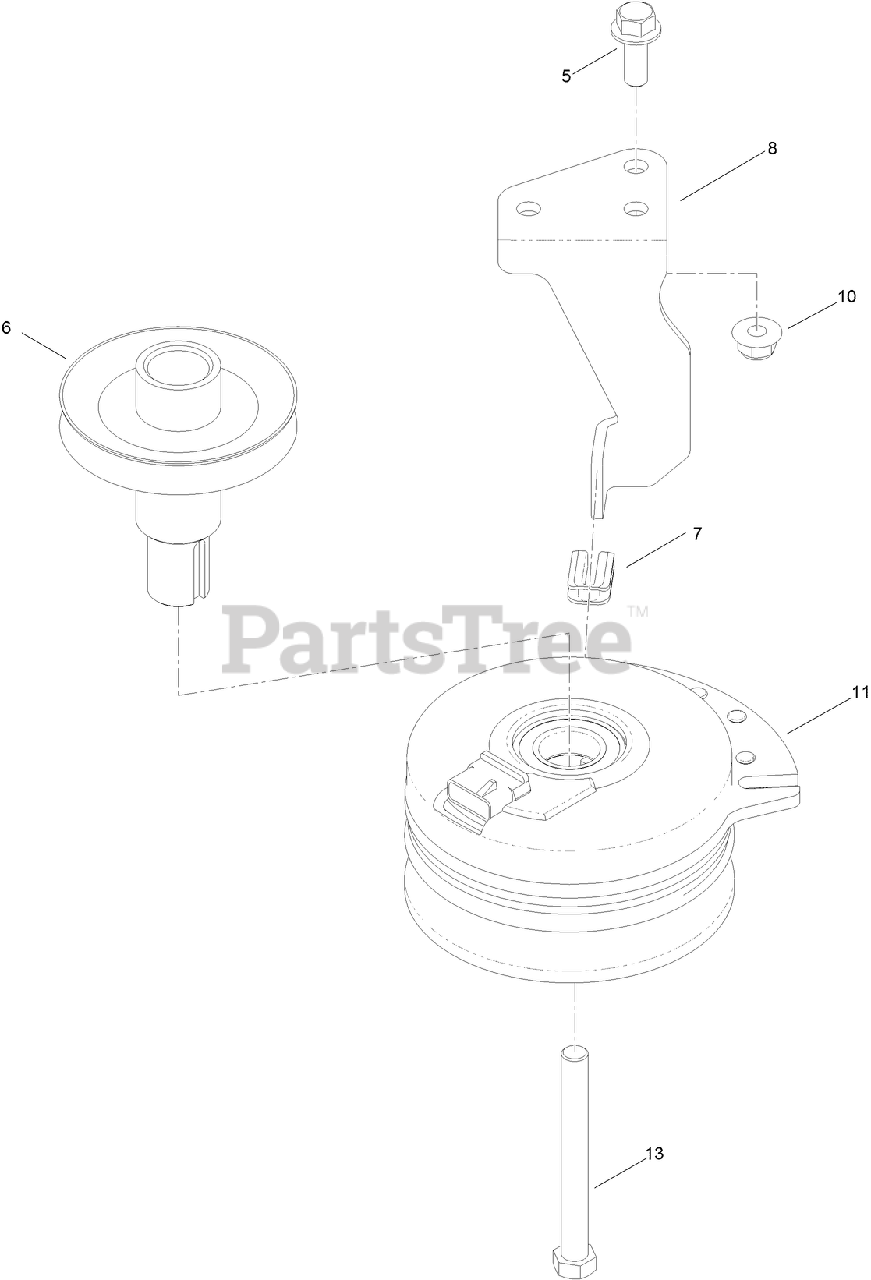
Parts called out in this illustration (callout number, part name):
5	SCREW-HHF
6	PULLEY-ENGINE
7	ISOLATOR-CLUTCH
8	STOP-CLUTCH (NARROW)
10	NUT-HF, NI
11	CLUTCH-ELECTRIC
13	SCREW-HH
